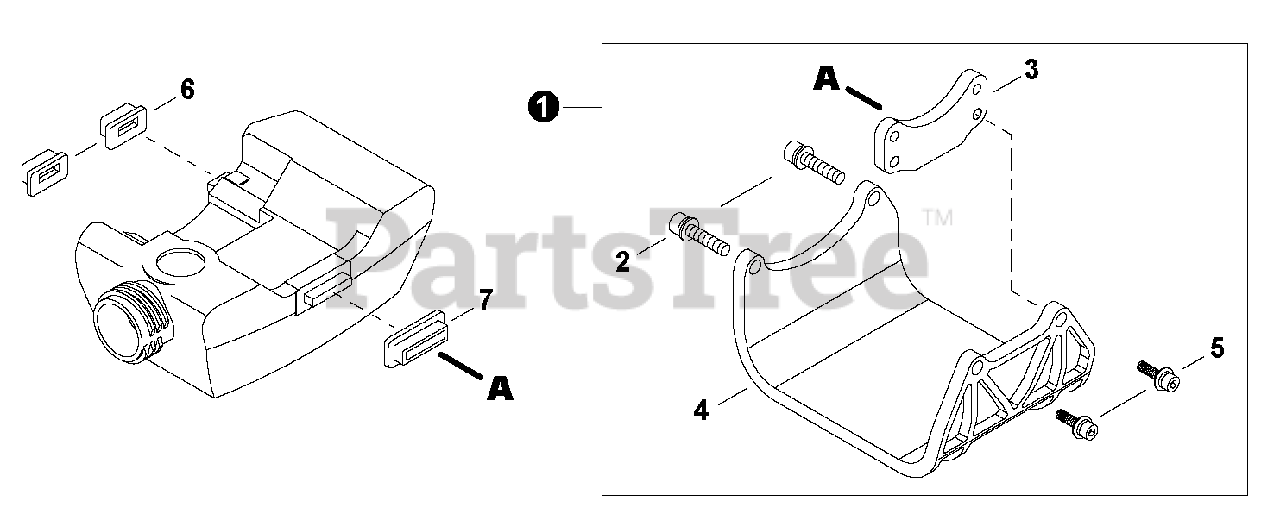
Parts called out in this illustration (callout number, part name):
1	Tank Guard Assy - Plastic
2	Bolt M5x30
3	Bracket, Fuel Tank
4	Guard, Fuel Tank
6	Cushion, Fuel Tank - Front
7	Cushion, Fuel Tank - Rear
